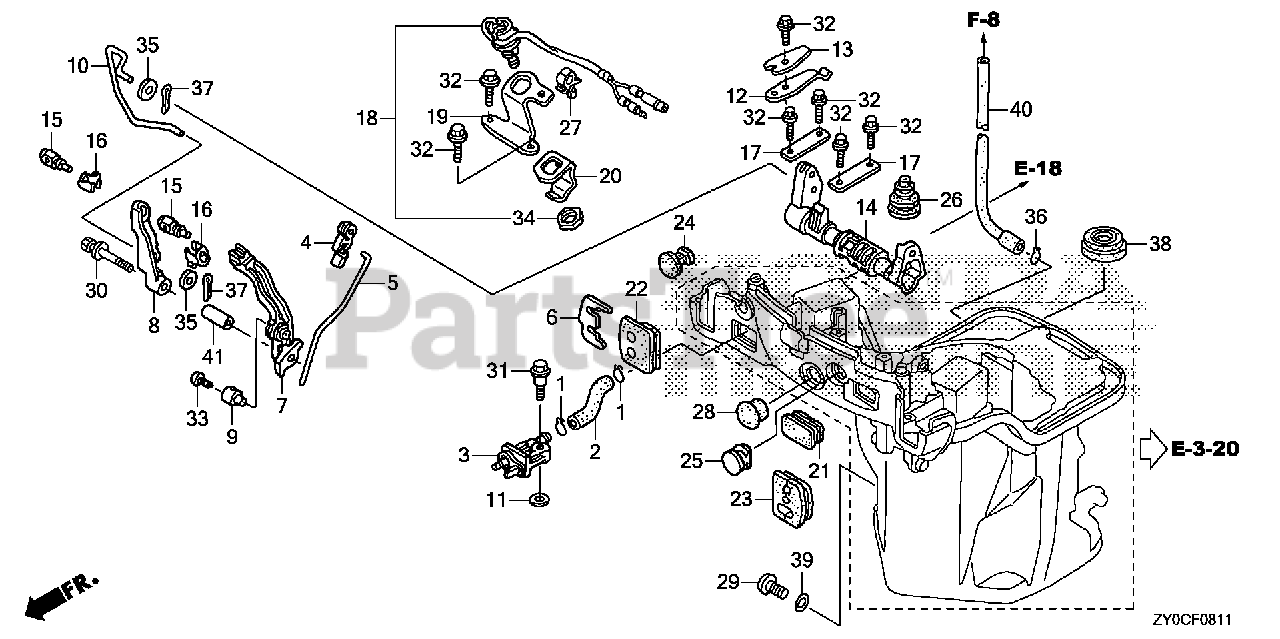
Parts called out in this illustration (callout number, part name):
1	CLIP, TUBE (ENGINE NO.)
2	TUBE A, FUEL (FKM)
3	CONNECTOR ASSY., FUEL (B)
4	LINKAGE, PIVOT
5	ROD, THROTTLE
6	PLATE, REMOTE CONTROL CABLE
7	ARM, THROTTLE REMOTE
8	ARM, SHIFT LINK
9	HOLDER, THROTTLE ROD
10	ROD, SHIFT LINK
11	WASHER, PIVOT
12	SPRING, CLICK
13	SPRING, CLICK ASSIST
14	SHAFT, SHIFT
15	PIVOT, SHIFT
16	PLATE, LOCK
17	PLATE, SHIFT SHAFT
18	SWITCH ASSY., NEUTRAL
19	BRACKET, NEUTRAL SWITCH
20	PLATE, NEUTRAL SWITCH
21	GROMMET G, OIL CASE
22	GROMMET A, OIL CASE
23	GROMMET B, OIL CASE (PT)
24	GROMMET F, OIL CASE
25	GROMMET D, OIL CASE
26	GROMMET E, OIL CASE
27	CLIP, BRAKE PIPE (A) (FOR NEUTRAL SWITCH)
28	CAP, HANDLE (LOWER)
29	BOLT, OIL CHECK
30	BOLT-WASHER (6X40)
31	BOLT, SPECIAL (6X22) (CT200)
32	BOLT, FLANGE (5X12) (CT200)
33	BOLT, RECESSED (5X8)
34	NUT, HEX. (20MM) Use up to Frame SN 1300359.
35	WASHER, PLAIN (7MM)
36	CLIP, TUBE (B10)
37	PIN, SPLIT (2.0)
38	SEAL, WATER (15X28X6) (ENGINE NO.)
39	O-RING (6.9X1.45)
40	TUBE, WATER CHECK
41	COLLAR, DISTANCE (6X11X27)
